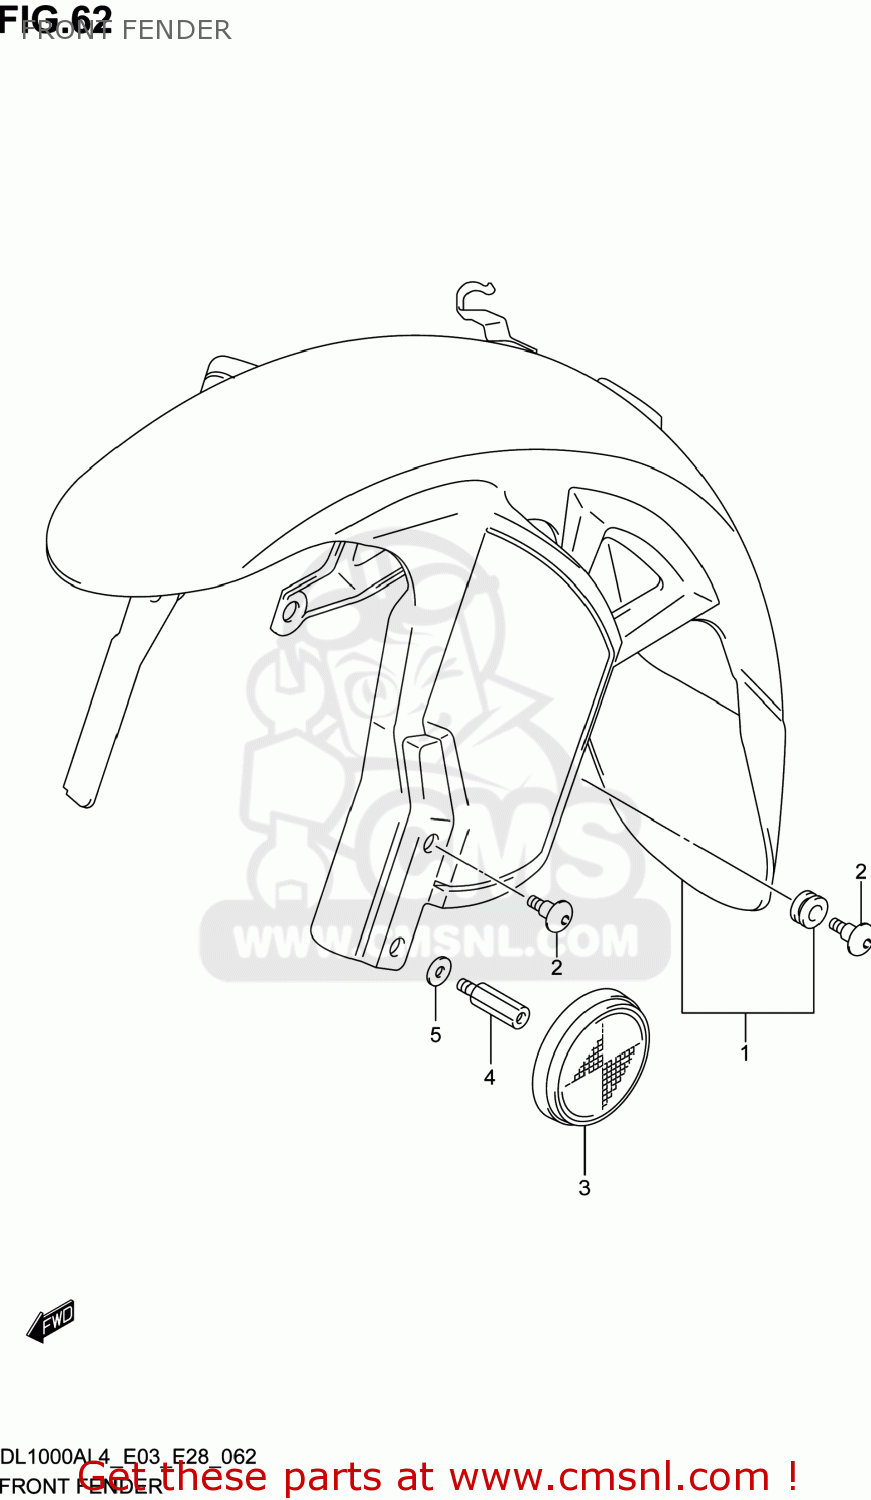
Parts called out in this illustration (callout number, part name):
1	FENDER ASSY,FRONT
2	SCREW
3	REFLEX REFLECTOR ASSY,FR SIDE
4	BOLT
5	WASHER(8.5X18X1)
